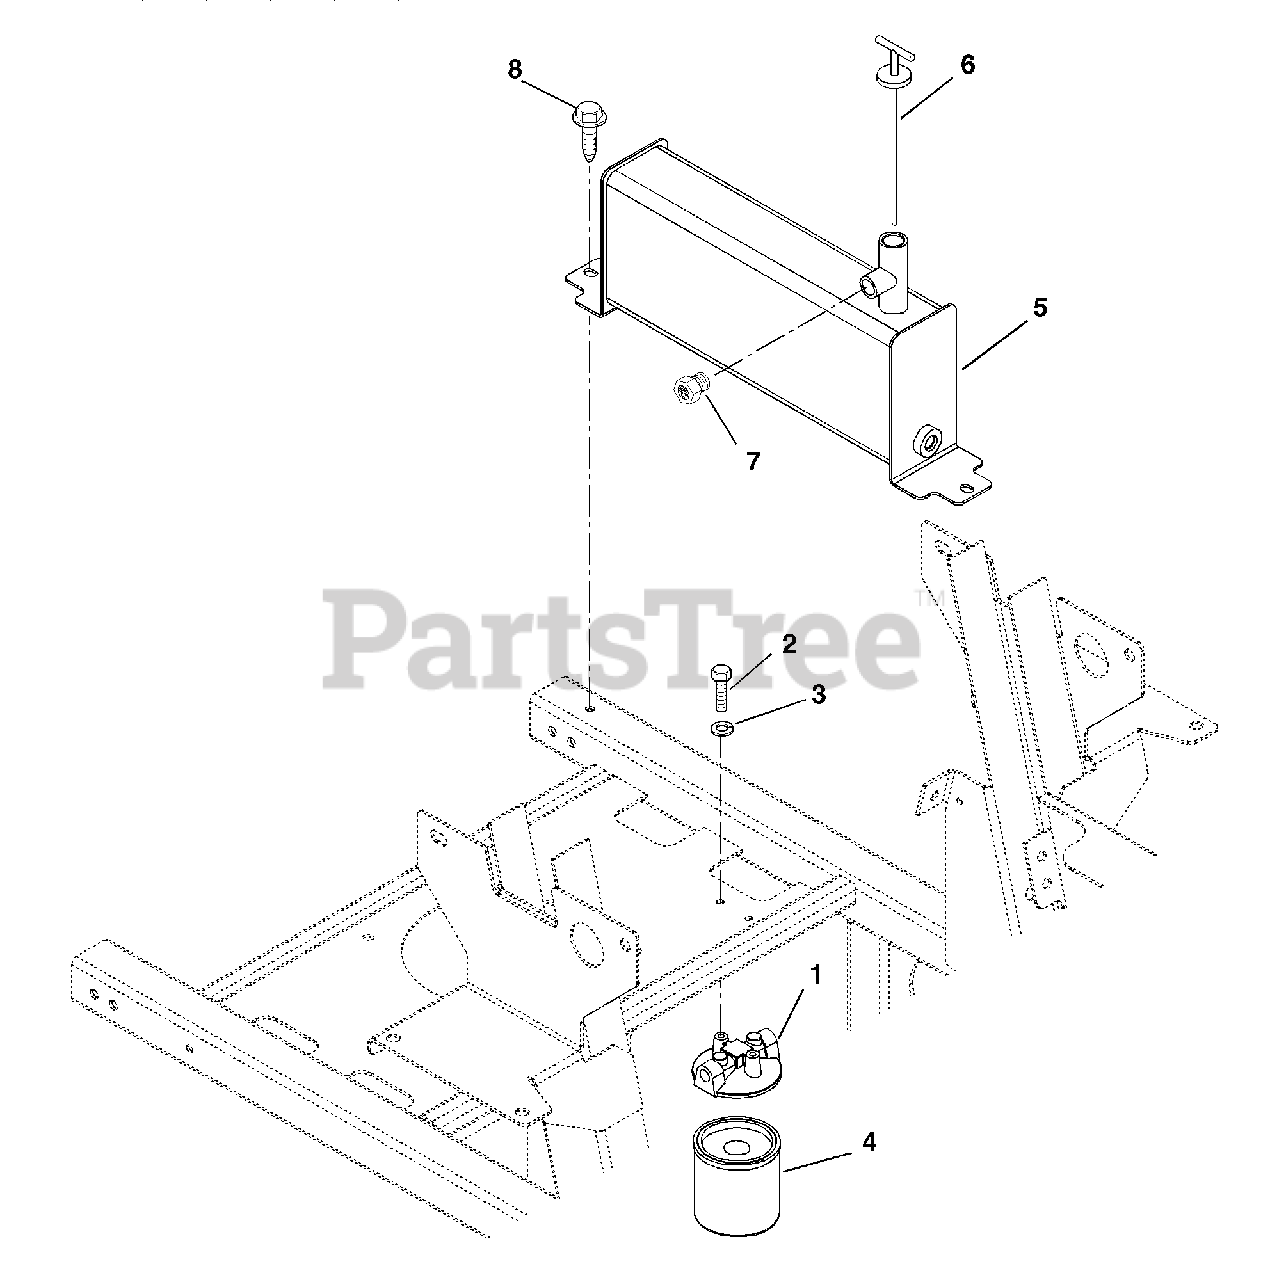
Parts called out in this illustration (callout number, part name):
1	Head-Filter
2	Bolt-Hex .25-20 x .50 Grade 5
3	Washer-Locking .25 x .062
4	Oil Filter
5	Tank-Hydraulic Weldment
6	Hydraulic Tank Dipstick
7	Plug-Breather .38
8	Screw-Tapping .38-16 x .75 Hex Washer Head
